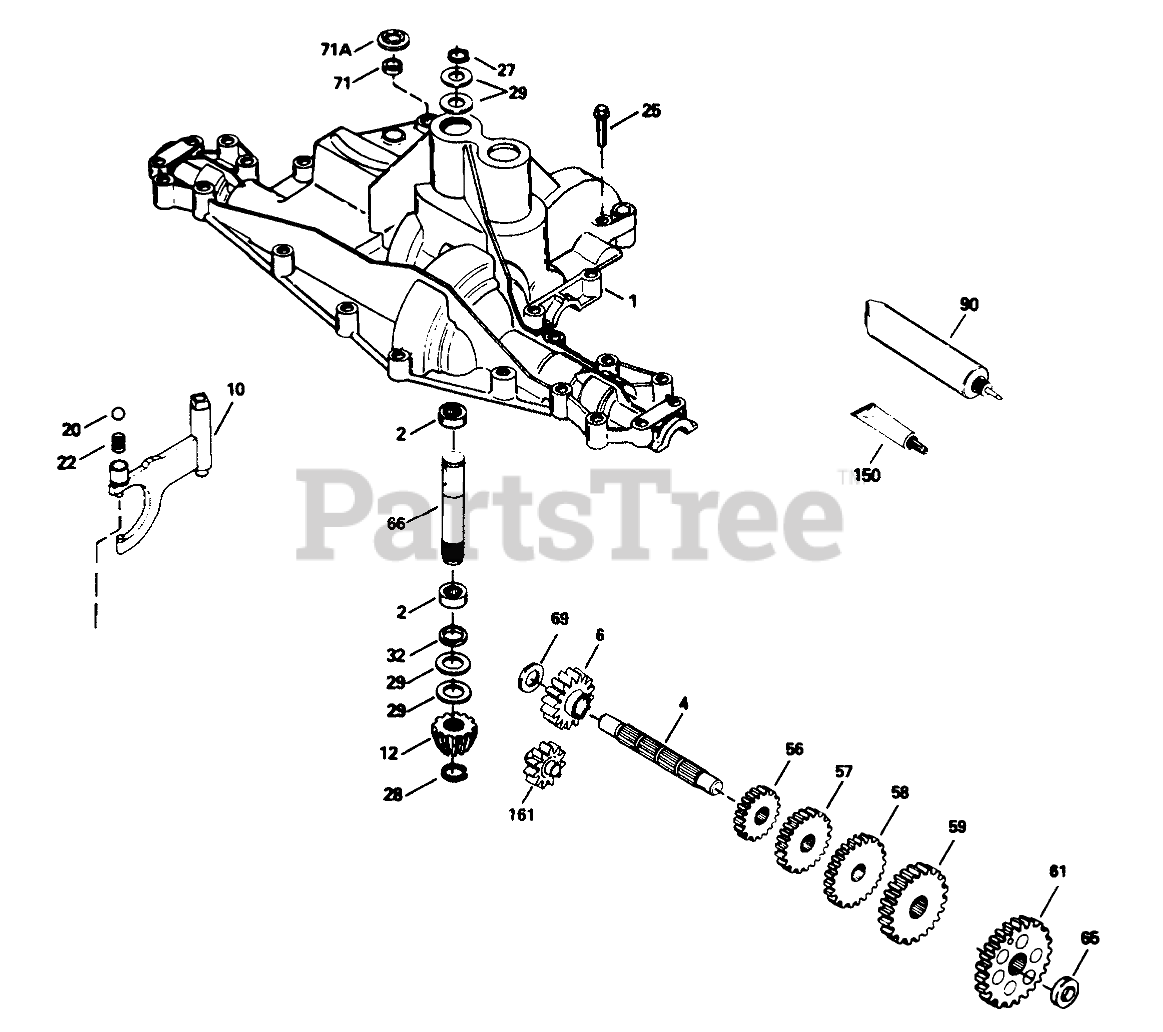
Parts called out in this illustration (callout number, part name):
1	Transaxle Cover
4	Countershaft
6	Spur Gear (16 Teeth)
10	Shift Rod & Fork
12	Bevel Pinion (14 Teeth)
20	Ball (3/8" dia.)
22	Spring
25	Ring Set (.020 O S)
27	Ring-Snap
28	Ring-Retainer
29	Washer
32	O Ring
56	Gear-Spur, 15 Teeth
57	Gear-Spur 23 Teeth
58	Spur Gear (21 Teeth)
59	Gear-Spur (30 teeth)
61	Spur Gear (34Teeth)
65	Washer
65A	Washer
66	Input Shaft (3.522" Ig.)
69	Thrust Washer
71	Cut Seal-Square
71A	Pushnut
90	Grease 32 Oz
150	Gasket Eliminator
161	Reverse Idler Assembly
